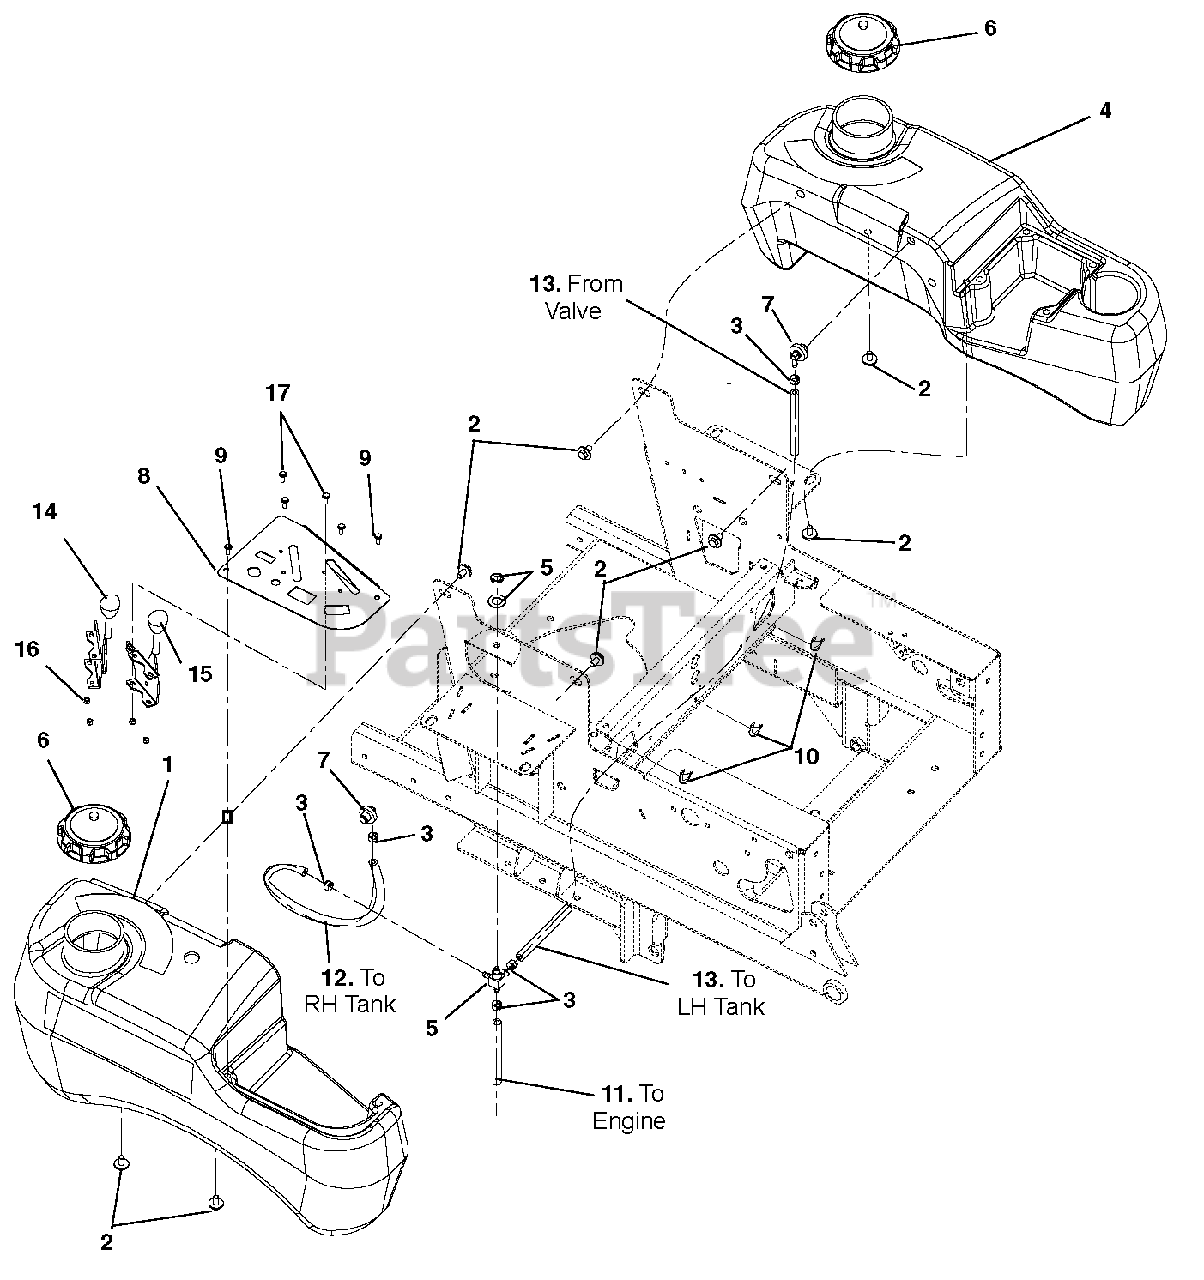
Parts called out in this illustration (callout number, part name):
1	Tank, Right Hand Fuel
2	Bolt, SEMS .31-18 X .62
3	Clamp, Fuel Line
4	Tank, Left Hand Fuel
5	Valve, Fuel
6	Cap, Fuel
7	Assembly, Medium Tank Fuel Pick-up
8	Panel, Control
9	Screw, Machine 10-24 x .50
10	Cable Tie
11	Hose, .25 Low-PERM Bulk Gas
12	Hose, .25 Low-PERM Bulk Gas
13	Hose, .25 Low-PERM Bulk Gas
14	Cable, Pro-Turn 100 Choke Control
15	Cable, Pro-Turn Throttle Control
16	Nut, Locking-Nylon 10-24 with Insert
17	Screw-Machine 10-24 x .50 Hex Washer Head
